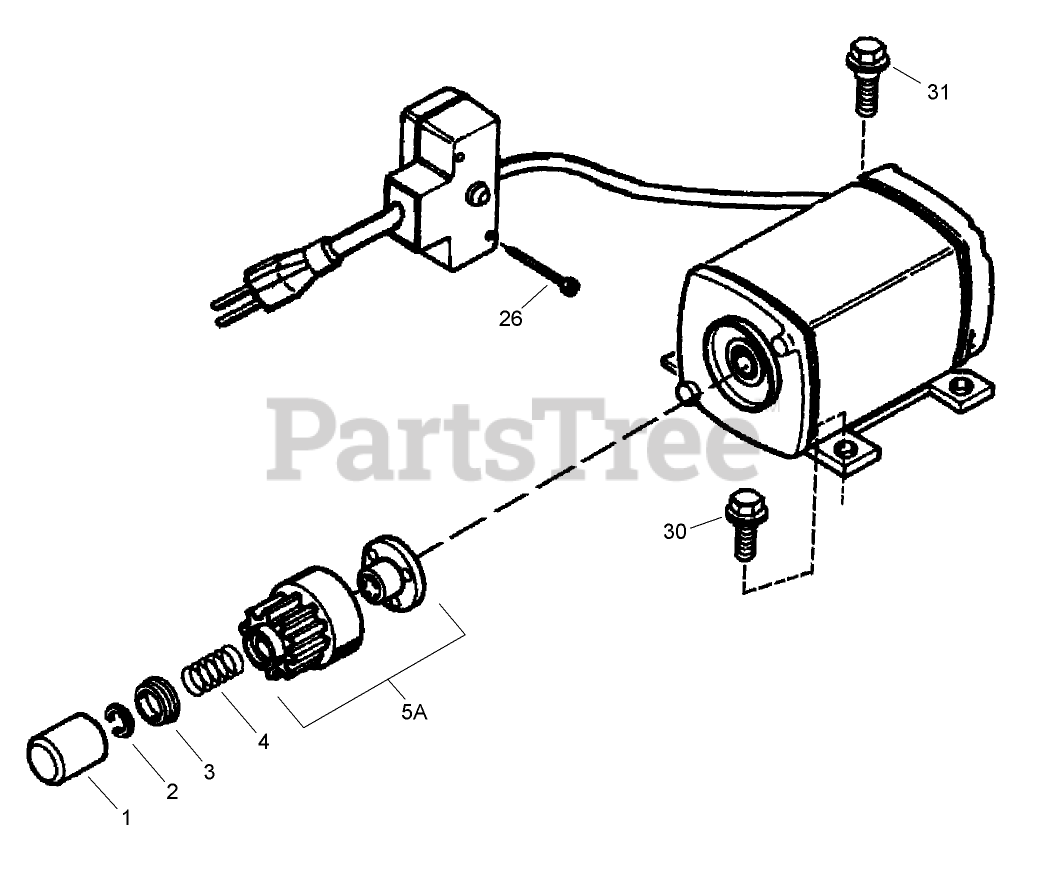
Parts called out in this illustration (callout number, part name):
1	Cover-Dust
2	Ring-Retainer
3	Retainer-Spring
4	Spring-Anti Drift
5A	Gear Nut (Incl. Ref.# 2)
26	Screw
26	Screw (12-16 x 5/8)
30	Screw
31	Screw (1/4-20x1/2)
